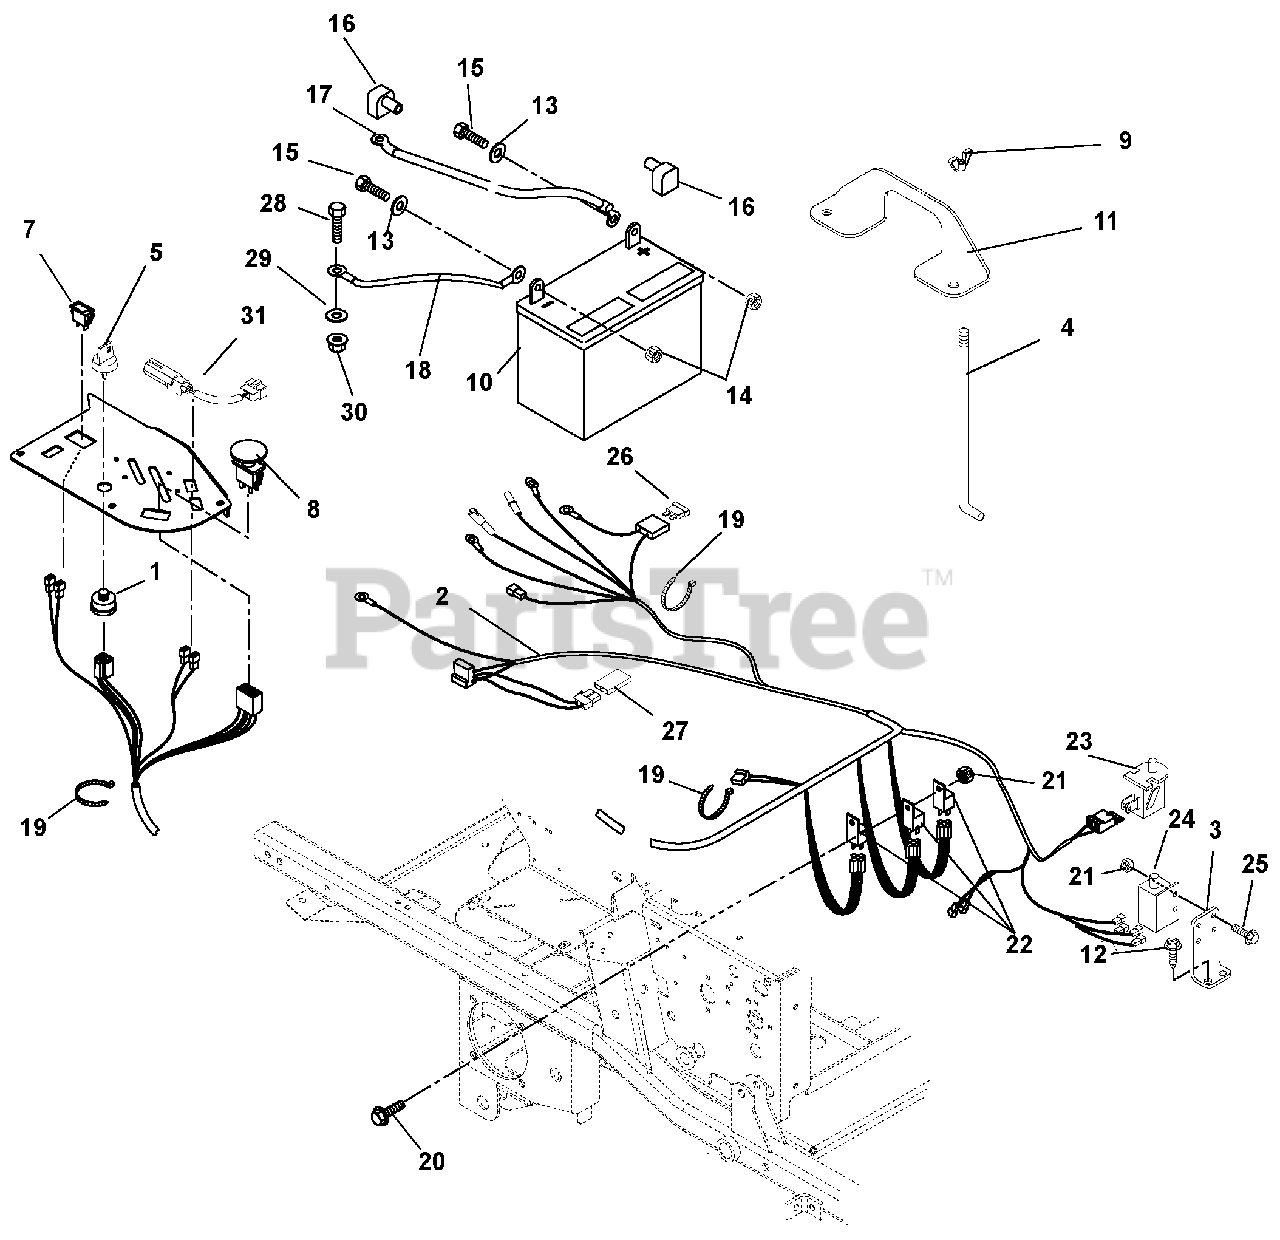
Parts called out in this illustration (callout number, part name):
1	Switch, Ignition
2	Harness, MZ Vertical A/C
3	Mount, Safety Switch
4	Rod, Battery Hold Down .25 x 6.62
5	Key, with Shield
6	Ignition Key Set
7	Hour Meter
8	Switch, PTO Clutch
9	Nut, Locking Wing .25-20
10	Battery, 12V
11	Hold Down, Battery
12	Screw, Tapping .25-20 x .50 Hex Washer Head
13	Washer, Flat Steel .281 x .620 x .065
14	Nut, Locking Top Flange .25-20
15	Bolt, Hex .25-20 x .75 Grade 5
16	Battery Terminal Boot, Red
17	Starter Cable 13 in.
18	Ground Cable
19	Cable Tie
20	Screw, Machine 10-24 x .50 Hex Washer Head
21	Nut, Locking Nylon 10-24 With Insert
22	Relay (Included with Harness)
23	Switch, Snap Mounting
24	Switch, Double Pole N.O./N.O.
25	Screw, Machine 10-24 x .75 Hex Washer Head
26	Fuse, 20 Amp (Included with harness)
27	Diode, Connector Shell
28	Bolt, Hex .31-18 x .75 Grade 5
29	Washer, Flat Steel .344 x .688 x .065
30	Nut, Locking Top Flange .31-18
31	Light, Indicator
